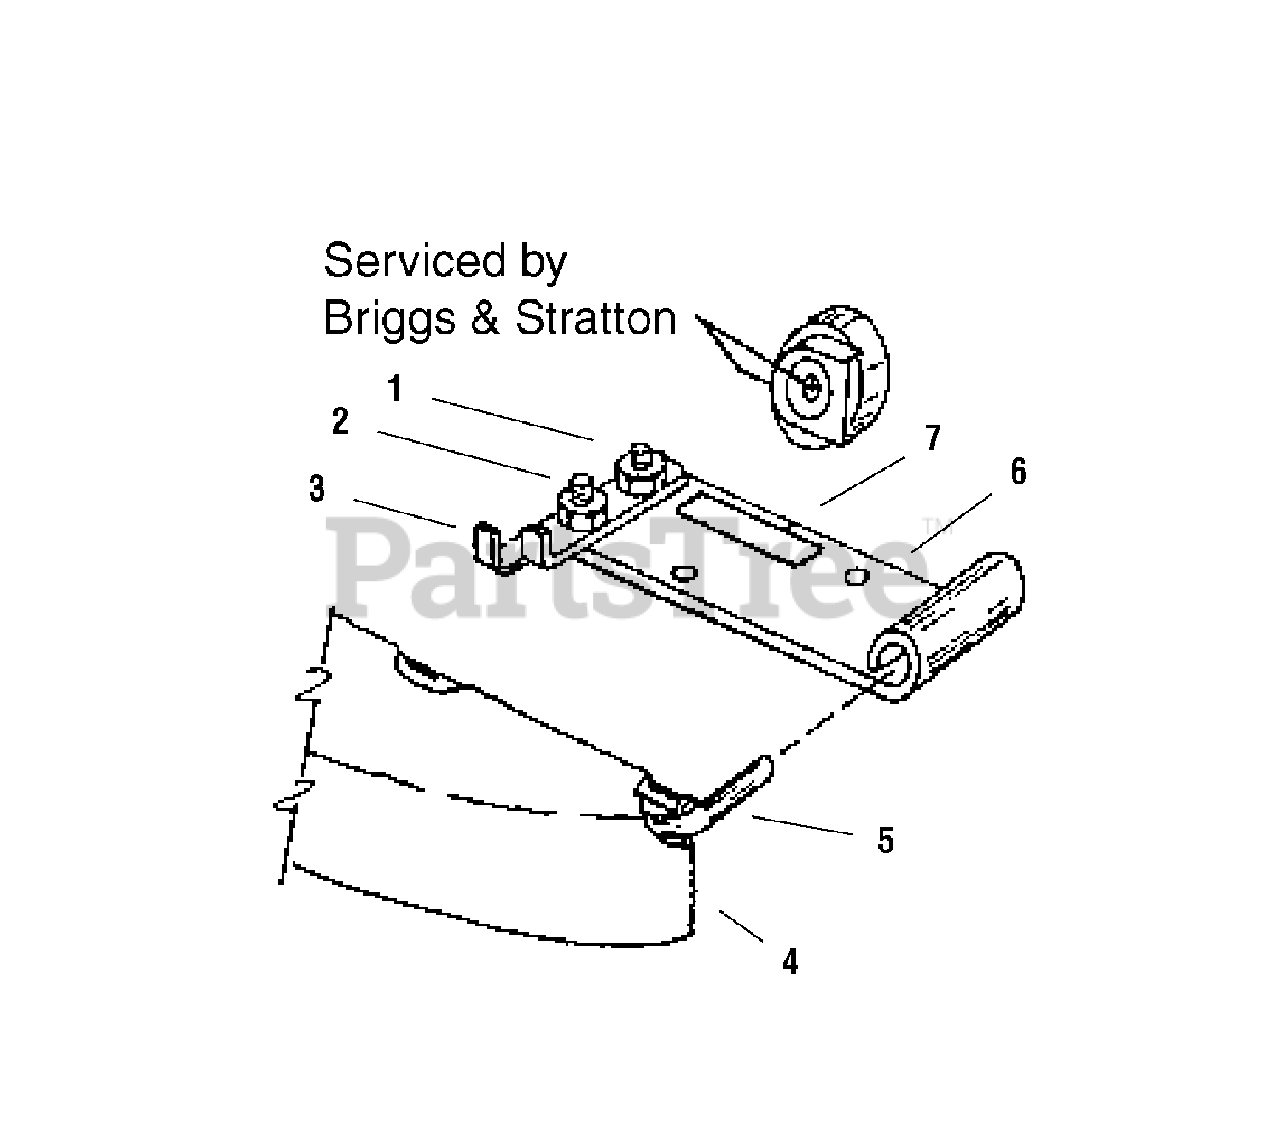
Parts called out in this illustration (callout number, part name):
1	NUT, Throttle
2	BOLT, Round Head
4	GRASS BAG
5	FRAME ASSEMBLY
7	DECAL, Caution
